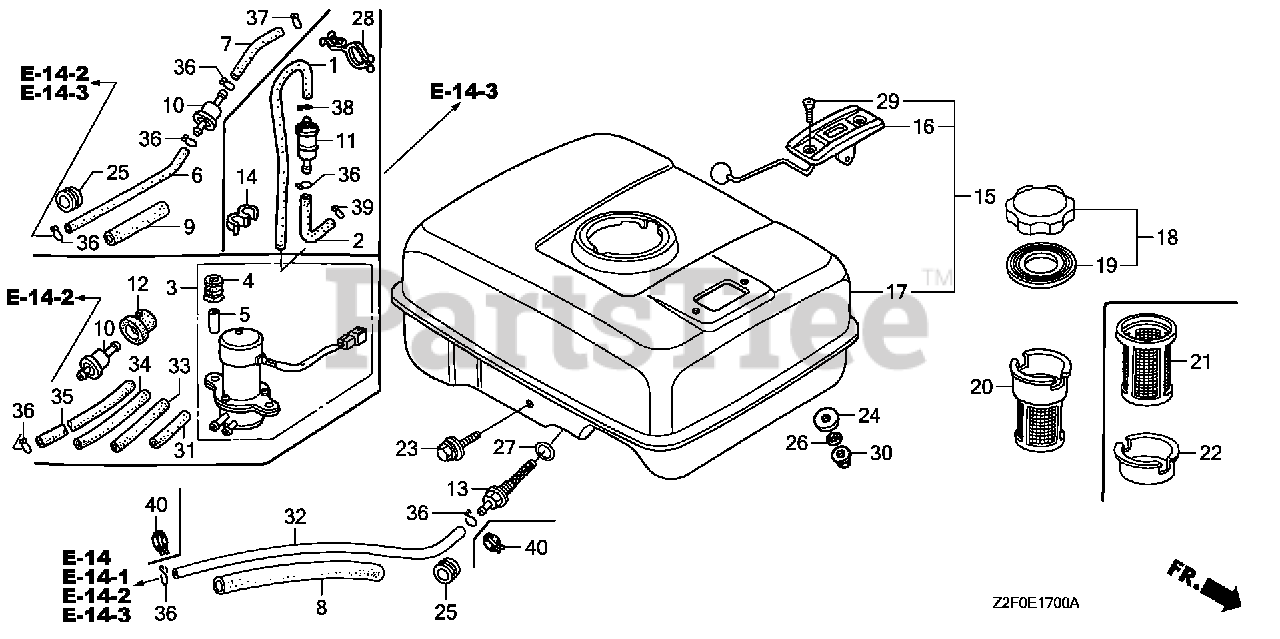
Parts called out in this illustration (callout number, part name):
8	RUBBER, SUPPORTER (107MM)
13	JOINT, FUEL TANK
17	TANK, FUEL *NH31* (MCKINLEY WHITE)
18	CAP, FUEL FILLER (CHROME PLATED)
19	GASKET, FUEL FILLER CAP (39X62X3) (TOUYOUSYA)
23	BOLT, FLANGE (6X29)
27	O-RING (13.5X1.5) (ARAI)
27	O-RING (14MM) (NOK)
30	NUT, FLANGE (6MM)
32	BULK HOSE, FUEL (4.5X3000) (4.5X140)
36	CLIP, TUBE (B8)
